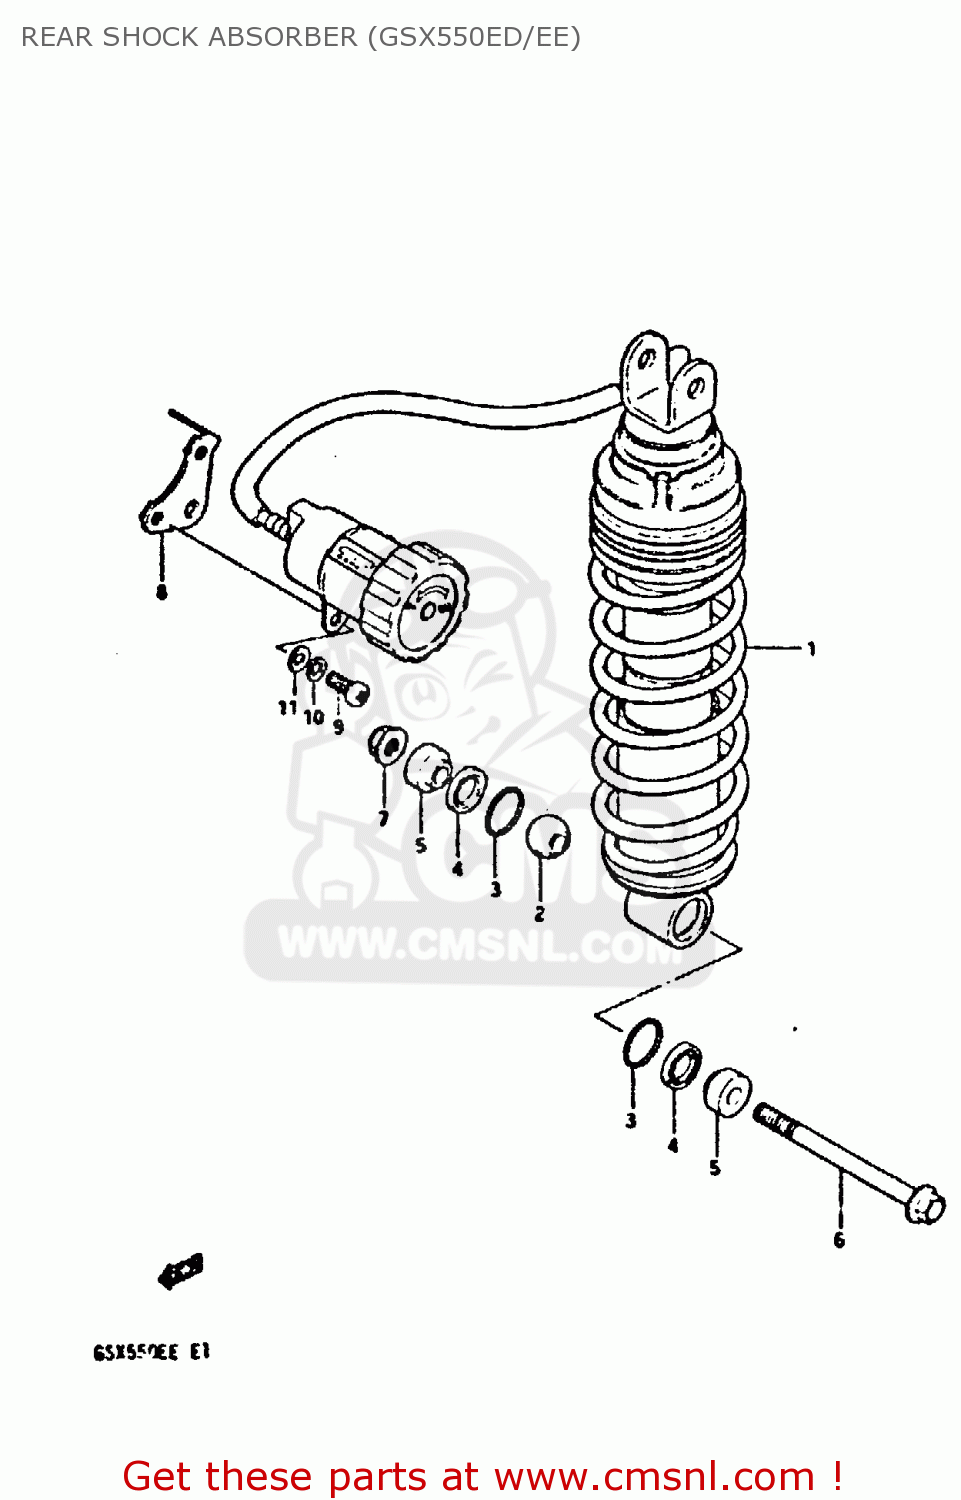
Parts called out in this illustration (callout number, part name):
1	SHOCK ABSORBER ASSY, REAR
2	BEARING(10X24X15)
3	RING
4	SEAL,DUST
5	COLLAR
6	BOLT(10X115)
7	NUT
8	BRACKET,RESERVOIR TANK
9	SCREW
10	LOCK WASHER
11	WASHER
